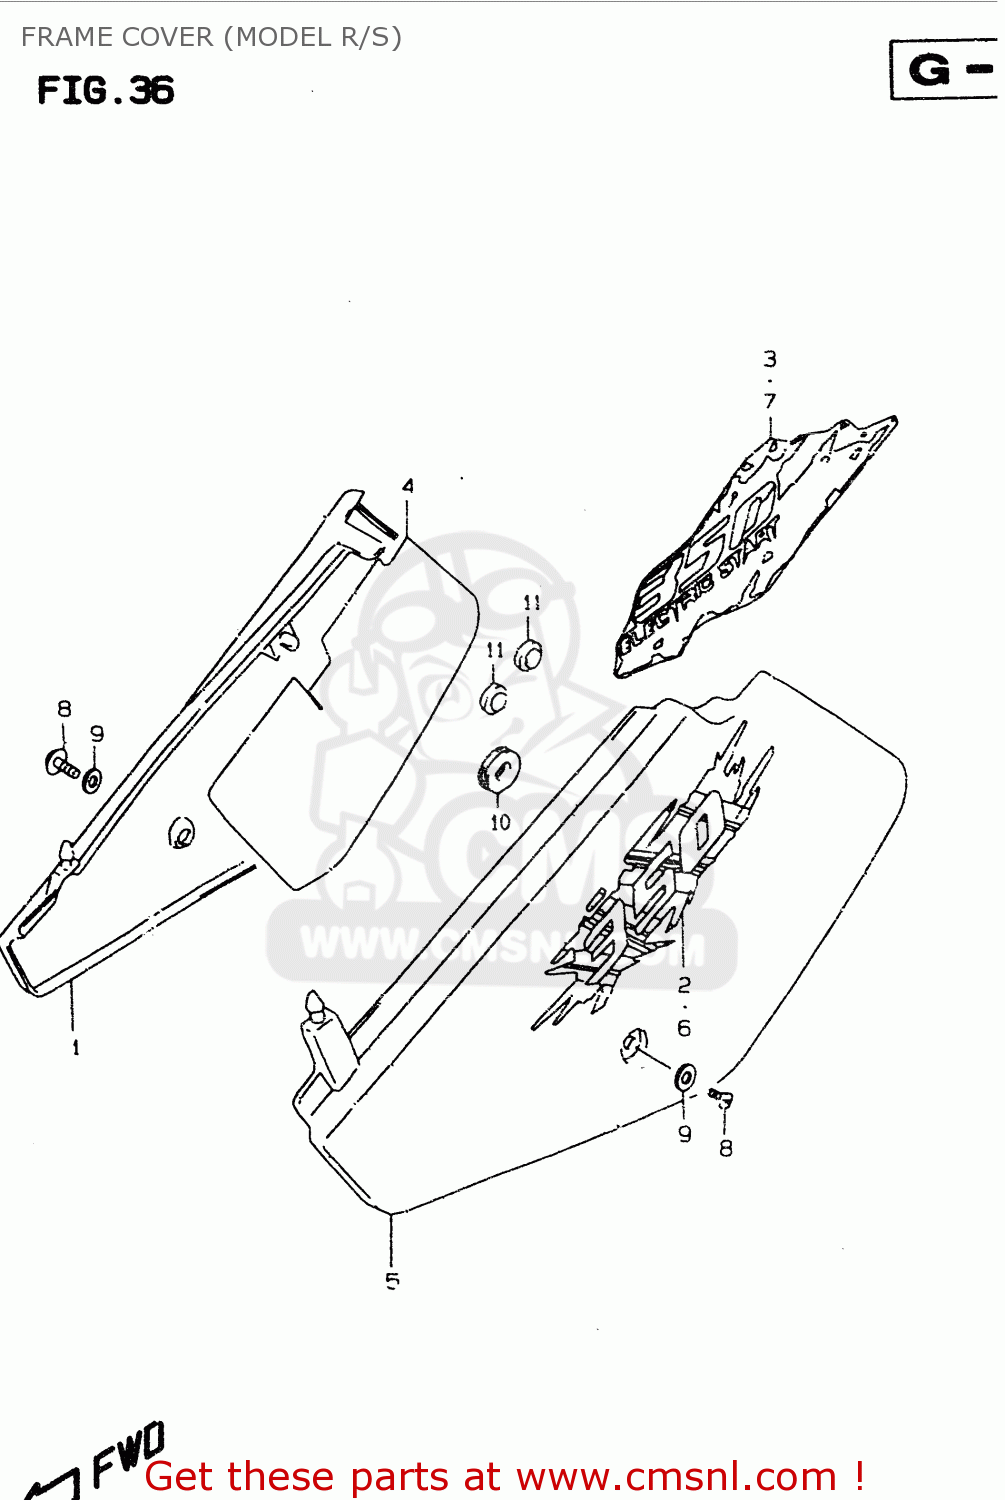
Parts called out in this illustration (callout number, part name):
1	COVER,FRAME,R(WHITE)
2	EMBLEM
3	TAPE, RH
4	SHIELD,FRAME COVER,R
5	COVER,FRAME,L(WHITE)
6	EMBLEM
7	TAPE,FRAME COVER,L
8	SCREW
9	WASHER
10	CUSHION
11	CUSHION
